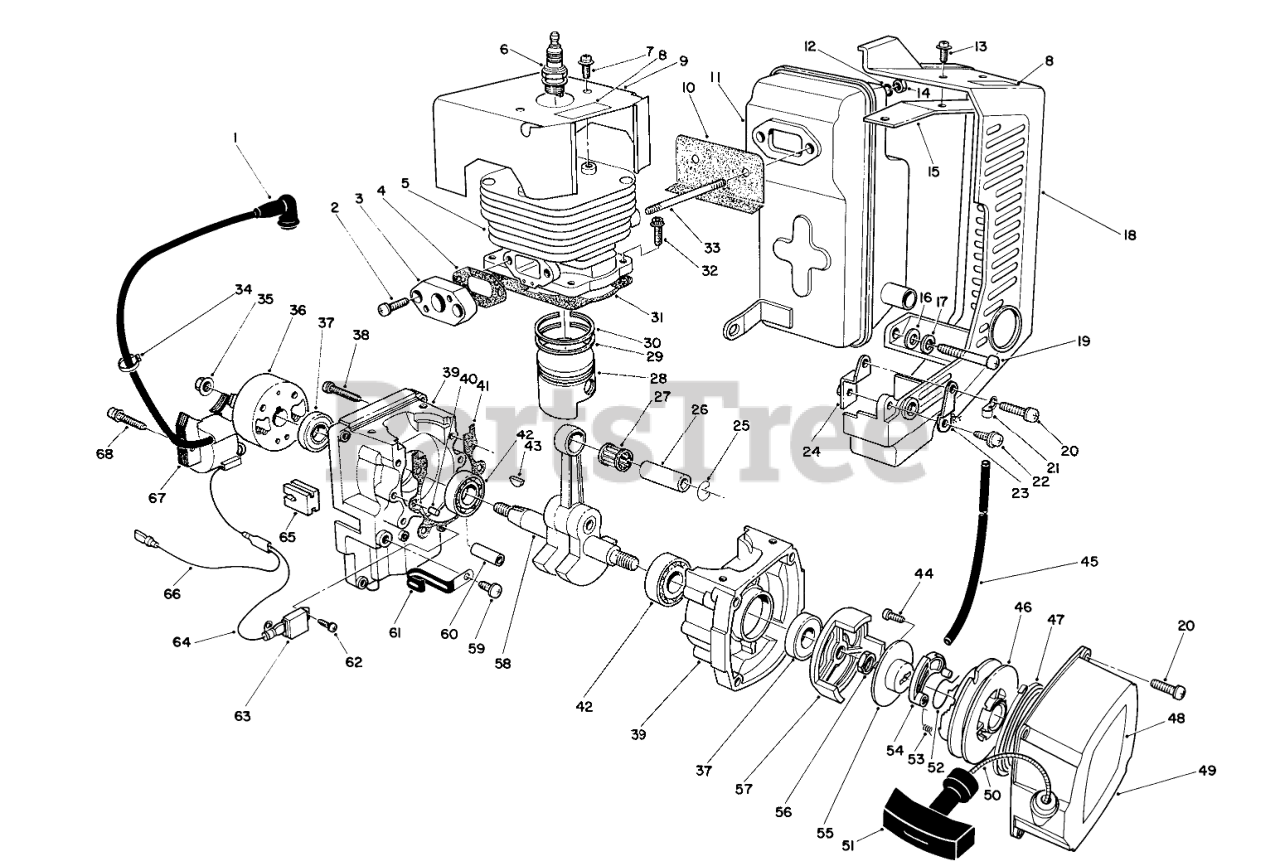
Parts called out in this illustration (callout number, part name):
1	CAP-PLUG
2	SCREW & WASHER
3	FLANGE
4	GASKET
5	CYLINDER
6	SPARK PLUG
7	SCREW & WASHER
8	Decal-Hot Surface
9	CYL COVER
10	MUFFLER GASKET
11	MUFFLER
12	Washer-Lock
13	SCREW & WASHER
15	BRACKET
16	Washer
17	Washer-Lock
18	MUFFLER COVER
19	Screw
20	SCREW & WASHER
21	Clamp
22	SCREW & WASHER
23	BRACKET
24	BRACKET
25	PISTON PIN CLIP
26	PISTON PIN
27	NEEDLE BEARING
28	Piston (Incl. Ref. #26)
29	TOP RING
30	TOP RING
31	GASKET
32	FLANGE BOLT
33	STUD BOLT
36	ROTOR
37	OIL SEAL
38	SCREW & WASHER
39	Crankcase Assembly (Incl. Ref. #38, 40)
40	Knock Pin
41	GASKET
42	BALL BEARING
43	Key-Woodruff
44	Screw
45	FUEL TUBE
46	Reel
47	Spring
48	Decal-41 CC Power Blower
49	Case-Starter
50	STARTER ROPE
51	STARTER KNOB
52	SPRING, FRICTION
53	SPRING, RETURN
54	Ratchet
55	FRICTION PLATE
56	J/S NUT
57	STARTER PULLEY
58	CRANKSHAFT ASM
59	Screw
61	Clamp
62	SCREW W/ WASHER
63	TRANSISTER UNIT
64	LEAD WIRE
65	Grommet
66	WIRE LEAD
67	IGNITION COIL
68	BOLT AND WASHER
